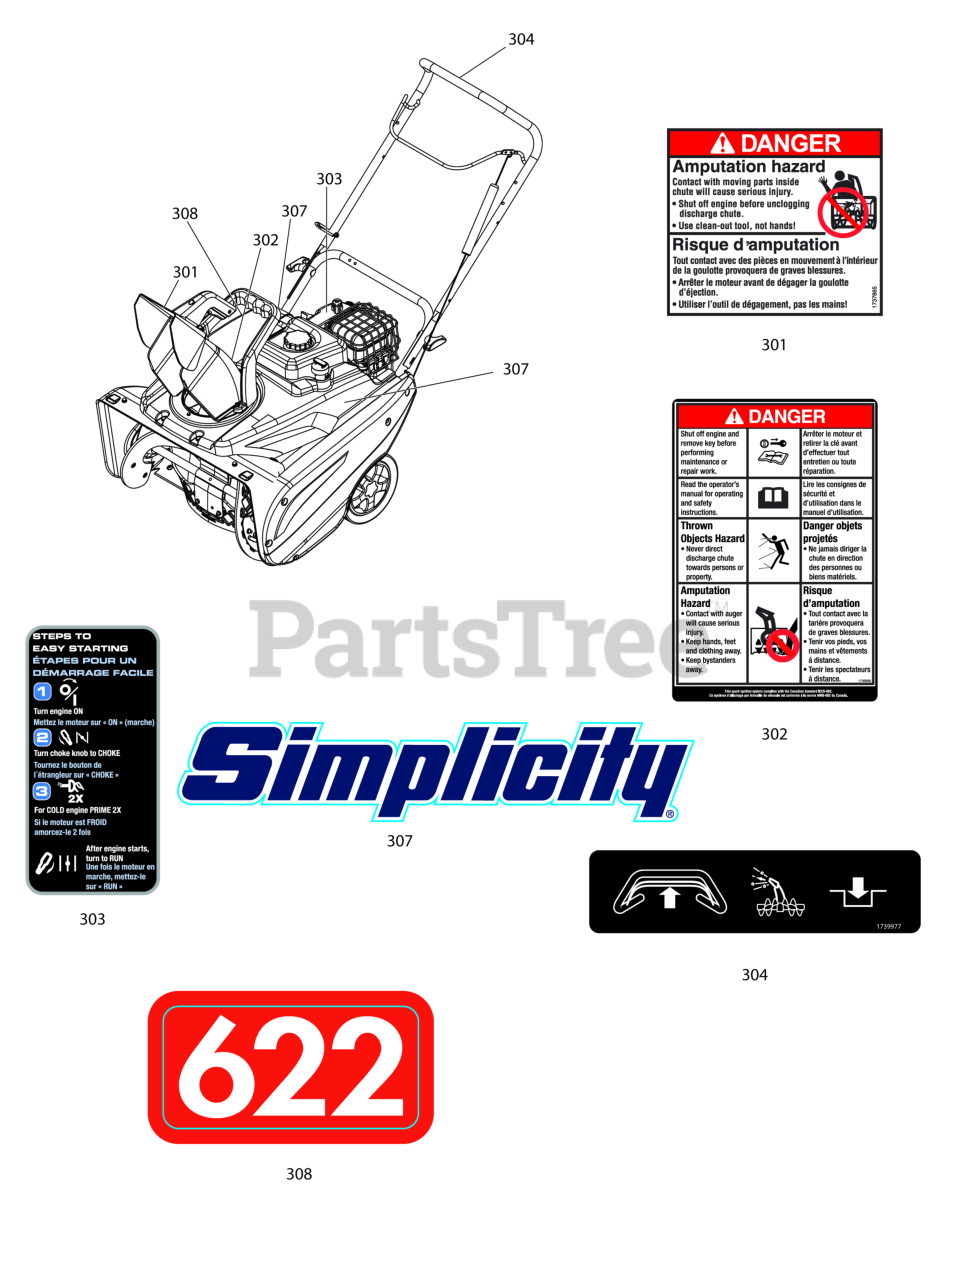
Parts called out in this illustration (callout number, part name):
301	DECAL, Danger Chute Warning, FR/ENG
302	DECAL, Chute, FR-EN
303	DECAL, 1-2-3 Start, FR-EN
304	DECAL, Bail Engagement
307	DECAL, Simplicity
